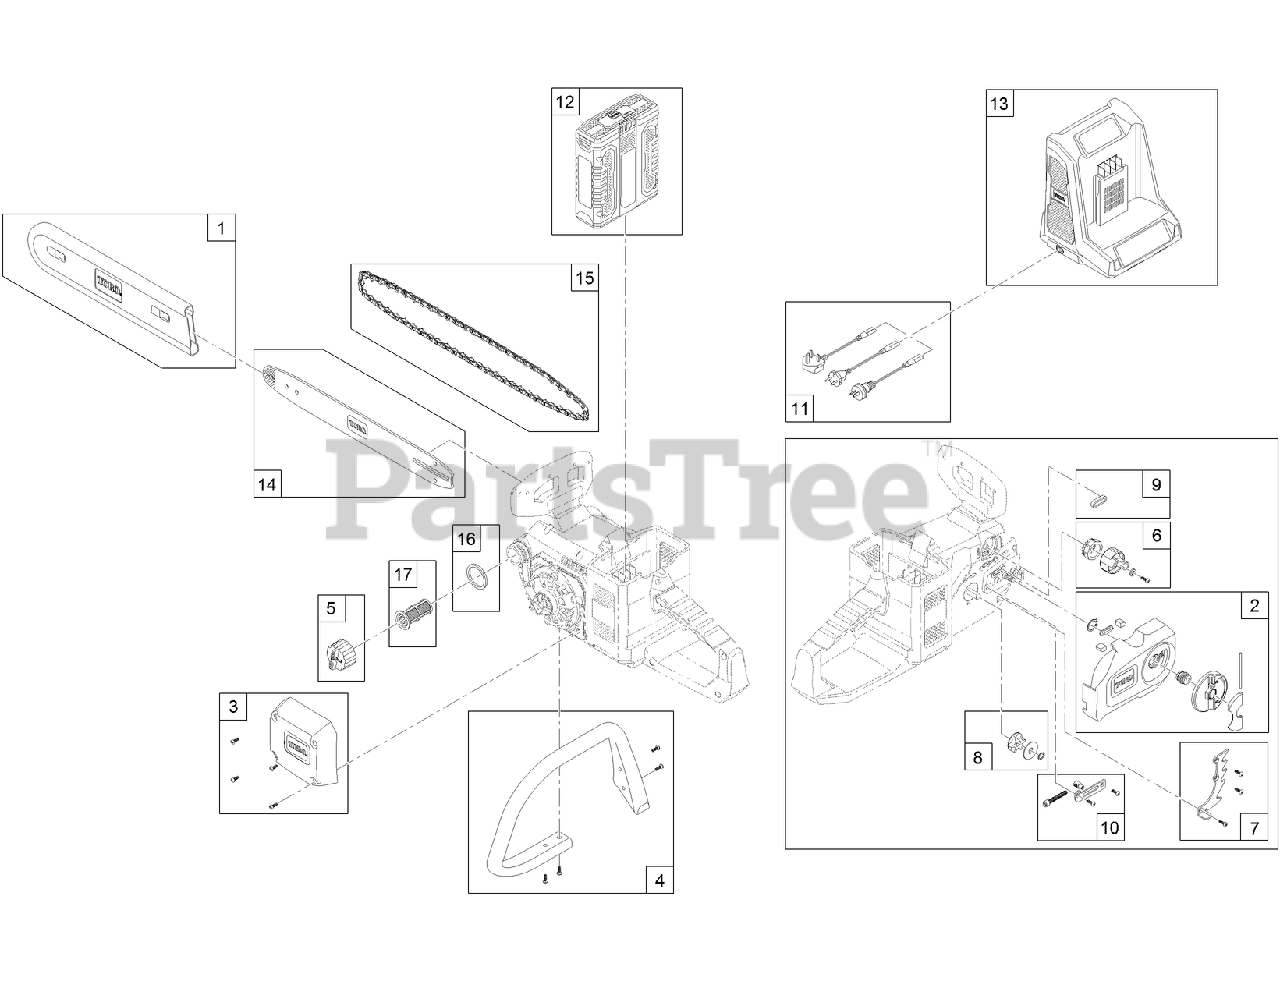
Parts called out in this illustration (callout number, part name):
1	SLEEVE-BAR/CHAIN
2	CHAIN Bar PANEL ASM
3	COVER-MOTOR
5	CAP-OIL, BAR
6	KNOB-ADJUSTER, Bar AND CHAIN
7	BUCKING TEETH BRACKET ASM
8	SPROCKET-DRIVE, CHAIN
9	GASKET-OIL, BAR/HOUSING
10	ADJUSTER-Bar PIN AND SCREW
12	BATTERY-40V MAX
13	CHARGER-BATTERY, 40V MAX
14	Bar-REPLACEMENT
16	GASKET-OIL CAP, BAR
17	Strainer-Oil, Bar
